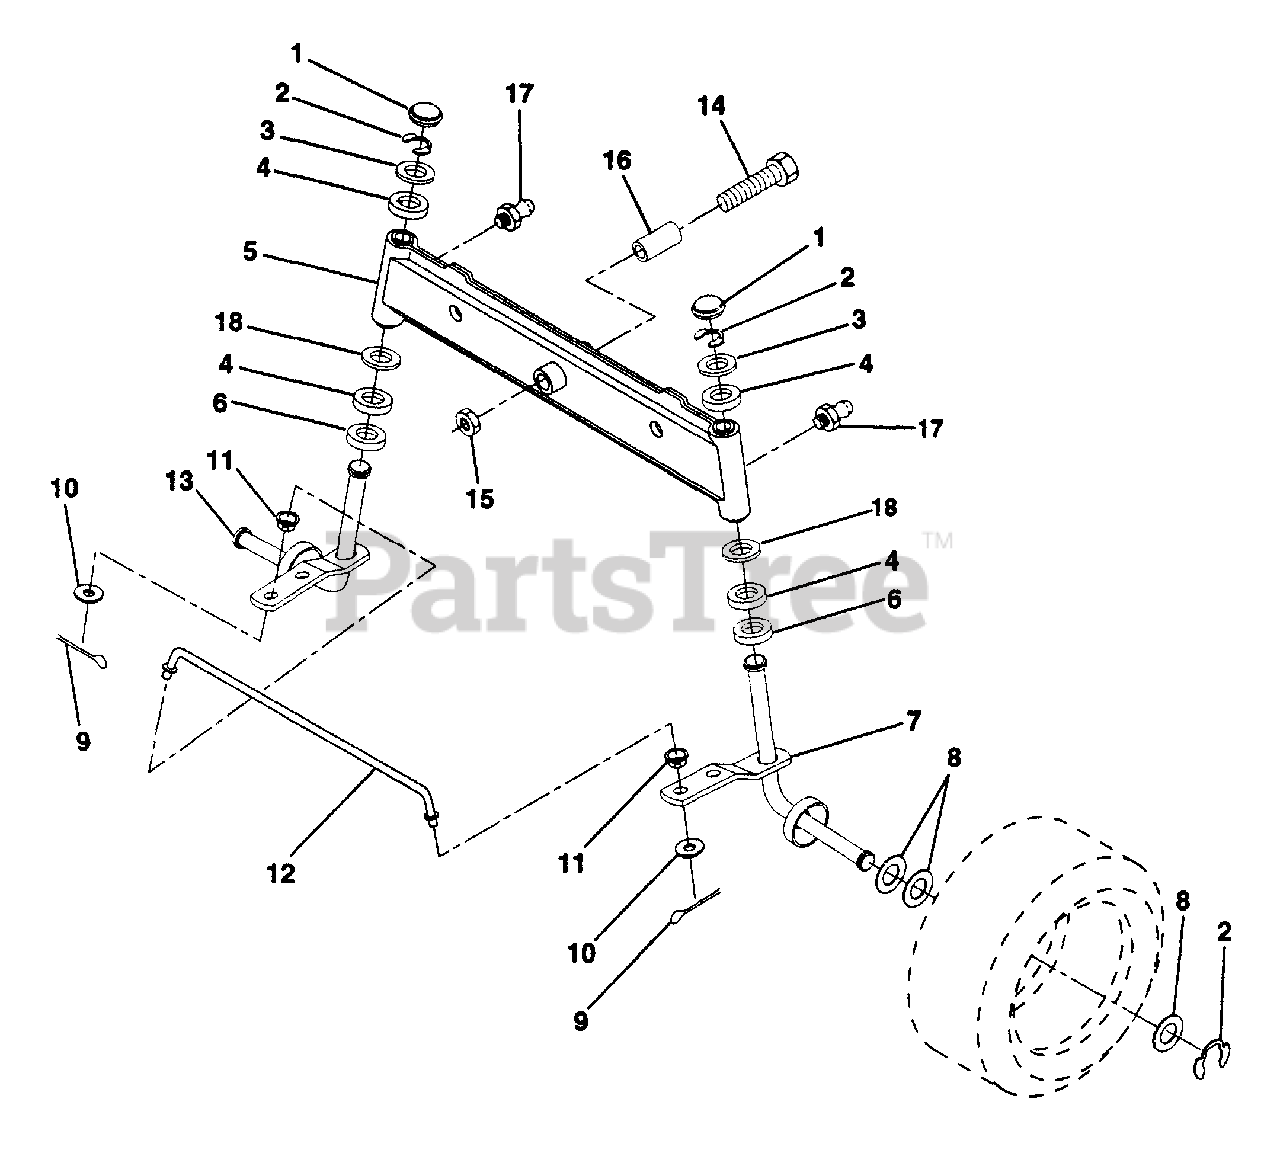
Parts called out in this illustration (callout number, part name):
1	Cap, Spindle
2	Ring, Clip
3	Washer 25/32 x 1-5/8 x 16 Gauge
4	Bearing
5	Axle, Front
6	Bearing, Thrust
7	Spindle Assembly, R.H.
8	Washer 25/32 x 1-1/4 x 16 Gauge
9	Pin, Cotter 1/8 x 3/4
10	Washer 13/32 x 13/16 x 16 Gauge
12	Tie Rod
13	Spindle Assembly, L.H.
14	Bolt Hex 5/8-11 Unc x 3-1/2
15	Nut Lock Flange 5/8-11 Unc
16	Spacer Bearing
17	Fitting Grease
18	Washer 27/32 x 1-1/4 x 16 Ga.
